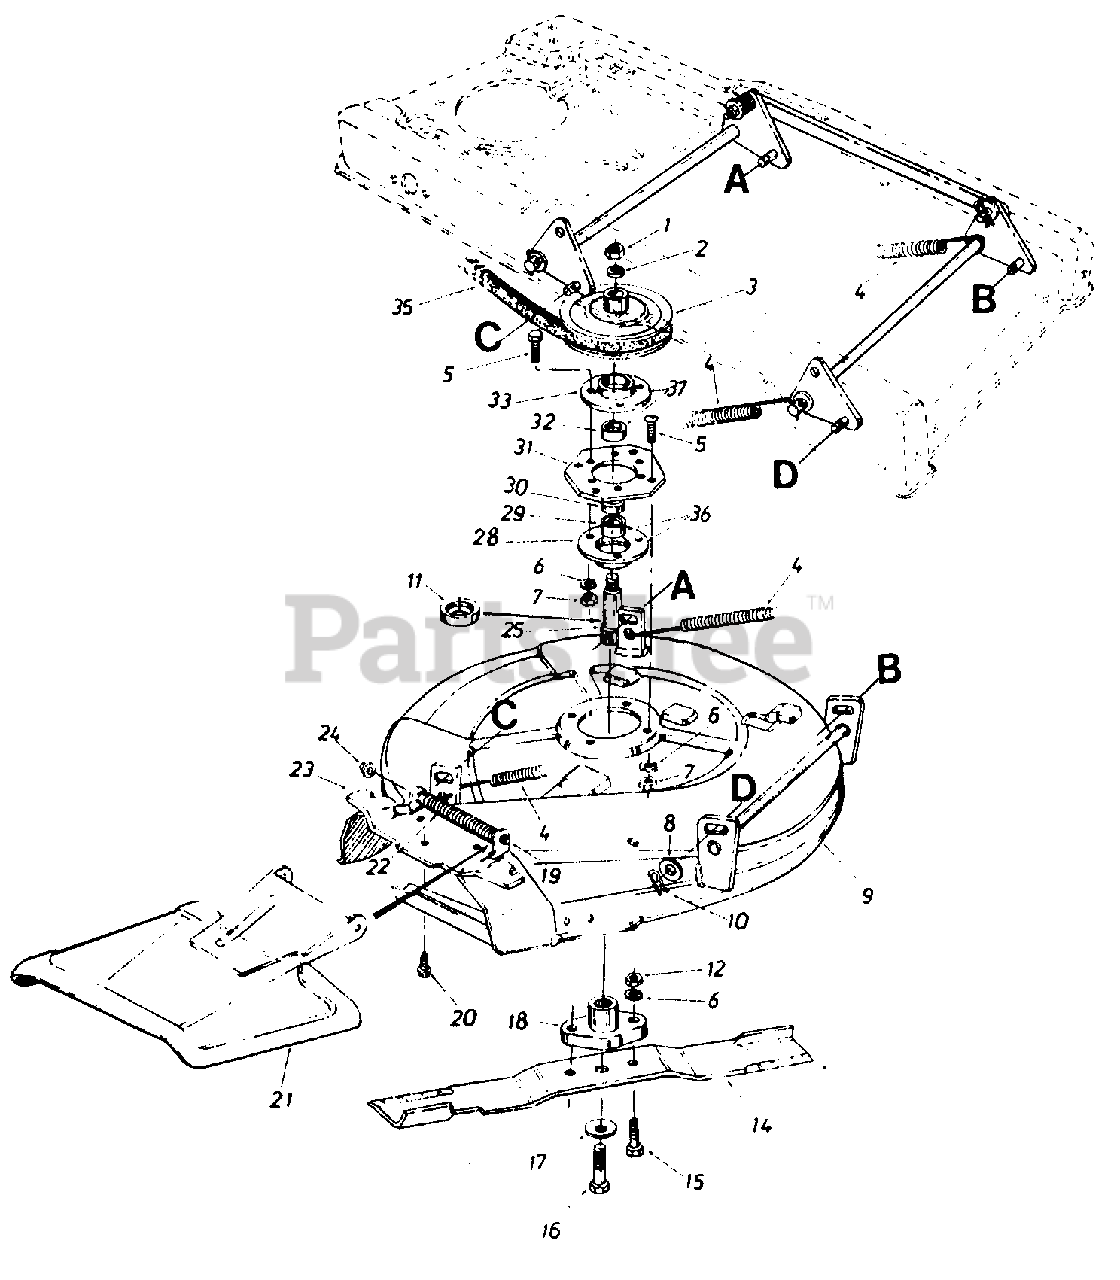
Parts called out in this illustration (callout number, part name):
1	Hex Jam Nut 5/16-18 Thd.
2	Bell-Wash. .630" I.D. x 1.25" O.D.
3	5/8" "V"-Pulley .75" I.D. x 9.5"
4	Extension Spring .56' O.D. x 1.0.5
5	Hex Bolt 5/16-18 x .75" Lg.'
6	L-Wash. 5/16" I.D.
7	Hex Nut 5/16-18 Thd.
8	Fl-Wash. .510" I.D. x 1.0" O.D.
9	26" Deck Ass'y.
10	Inter. Cotter Pin 1/2" Dia.
11	Bearing Shield
12	Hex Nut 5/16-24 Thd.
14	Blade 26"
15	Hex Bolt Special 5/16-24 x 1.0" Lg.
16	Hex Bolt 3/8-24 x 1.00' Lg.
17	Bell-Wash. .391' I.D. x 1.38" O.D.
18	Blade Adapter
20	Hex Wash. Hd. TT-Scr. 1/4-20
21	Chute Cover Ass'y.
22	Torsion Spring
23	Adapter Plate
24	Cap Speed Nut l/4" Rod
25	Blade Spindle 4.42" Lg.
28	Bearing Housing 1.85
29	Ball Brg. .787" I.D. x 1.85" O.D.
30	Spacer 1.0" O.D. x .790" I.D. x.350" Lg.
31	Spindle Mounting Plate
32	Ball Brg. .787" I.D. x 1.85" O.D.
33	Open Brg. Housing 1.85
35	"V"-Belt
36	Brg. Hsg Ass'y
37	Brg. Hsg. Ass'y.
